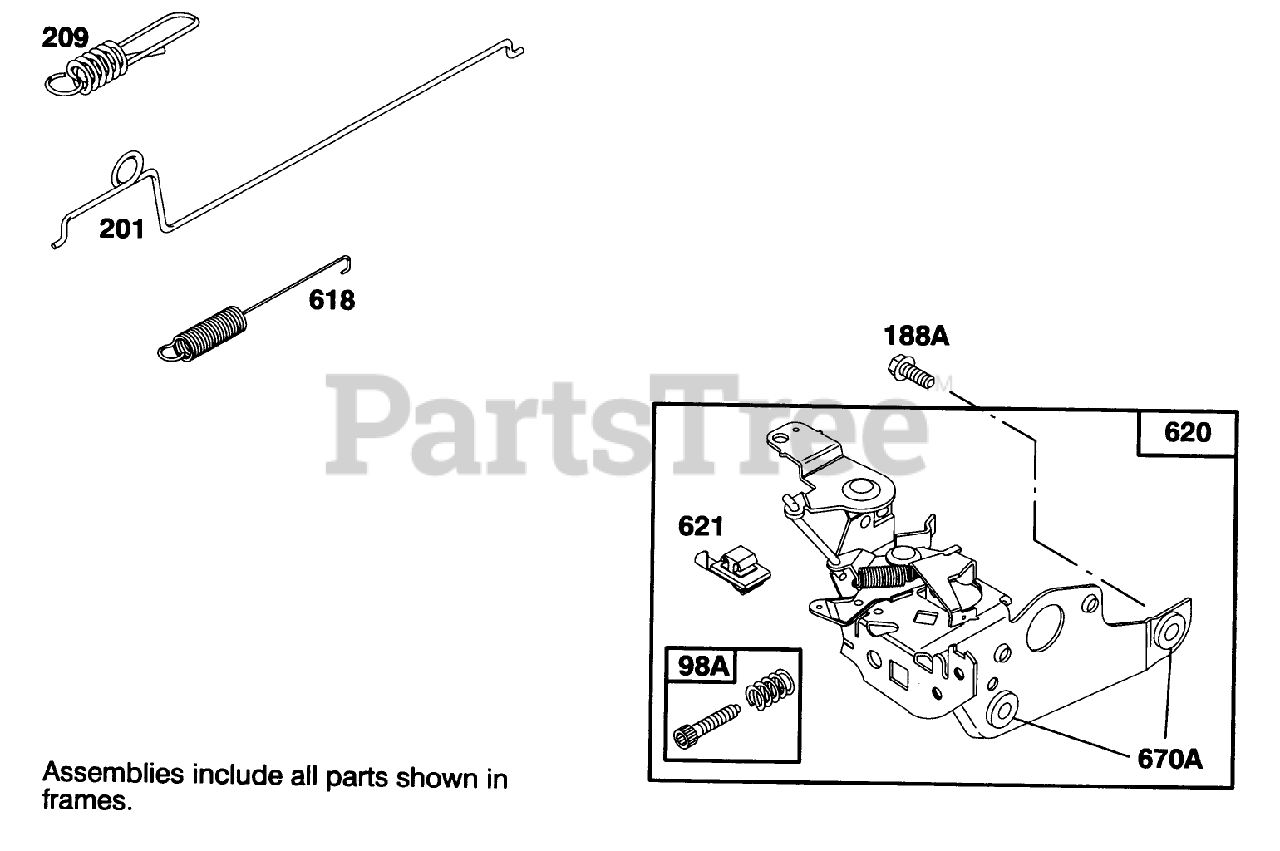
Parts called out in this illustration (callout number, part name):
98A	Screw Assy.
188A	Screw-Hex.
201	Link-Govemor
209	Spring-Governor
618	Spring-Choke
620	Bracket-Control
621	Switch
670A	Spacer
